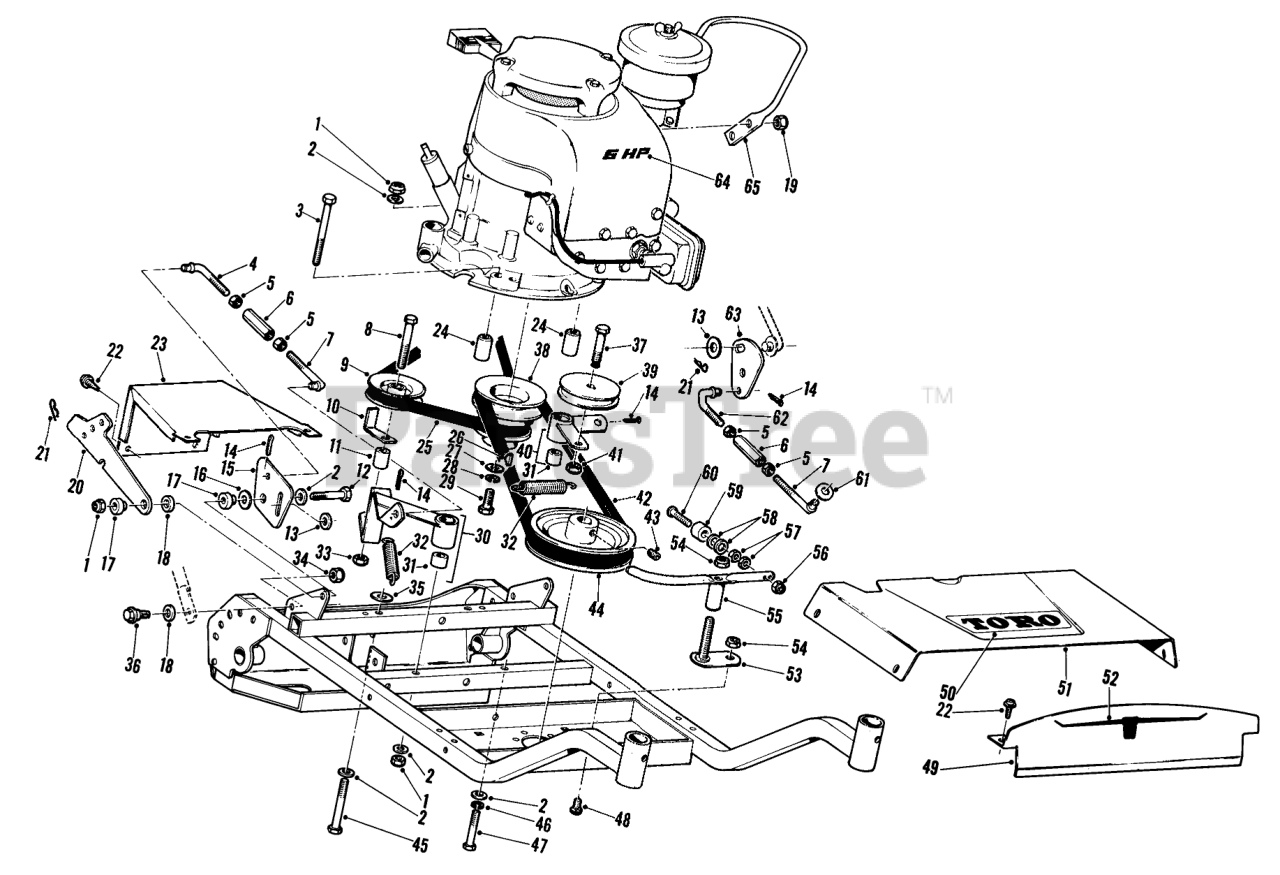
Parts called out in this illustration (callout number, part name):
1	Nut
2	WASHER-PLAIN
3	SCREW-HH
4	TRACTION LINK
5	NUT-HEX
6	CONTROL ROD SLEEVE
8	SCREW-HH
9	IDLER PULLEY R
11	Spacer
12	5/16-18 X 1-3/4 SCREW
13	Spacer
14	PIN-COTTER
15	Bell Crank
16	WASHER
17	PIVOT
18	SPACER
19	NUT-LOCK NI
20	Latch
21	PIN-COTTER
22	10-16 X 3/8 THDG SCREW
23	Rear Shroud
24	ENGINE PIVOT SPACER
25	V-BELT
26	KEY-WOODRUFF
27	WASHER-FLAT
28	WASHER-LOCK
29	SCREW-HH
30	Arm & Bushing Assy.
31	BUSHING
32	EXTENSION SPRING
33	NUT-HEX
34	Nut
35	WASHER
36	SCREW-SHOULDER
37	Screw
38	Pulley
39	PULLEY B
40	Arm & Bushing Assembly
41	Nut
42	CUTTER BELT
43	SCREW-HSH
44	CUTTER PULLEY
45	SCREW-HH
46	WASHER-LOCK
47	SCREW-HH
48	SCREW-CARR
49	Shroud Panel
50	Decal
51	FRONT SHROUD R
52	Decal
53	Base Pivot
54	NUT-HEX
55	Brake Arm
56	NUT-LOCK, NI
57	NUT-HEX
58	WASHER-FLAT
59	BUMPER
60	10-24X1-1/2 RND HD MS
61	WASHER
62	CUTTER LINK
63	Bell Crank
64	Decal
